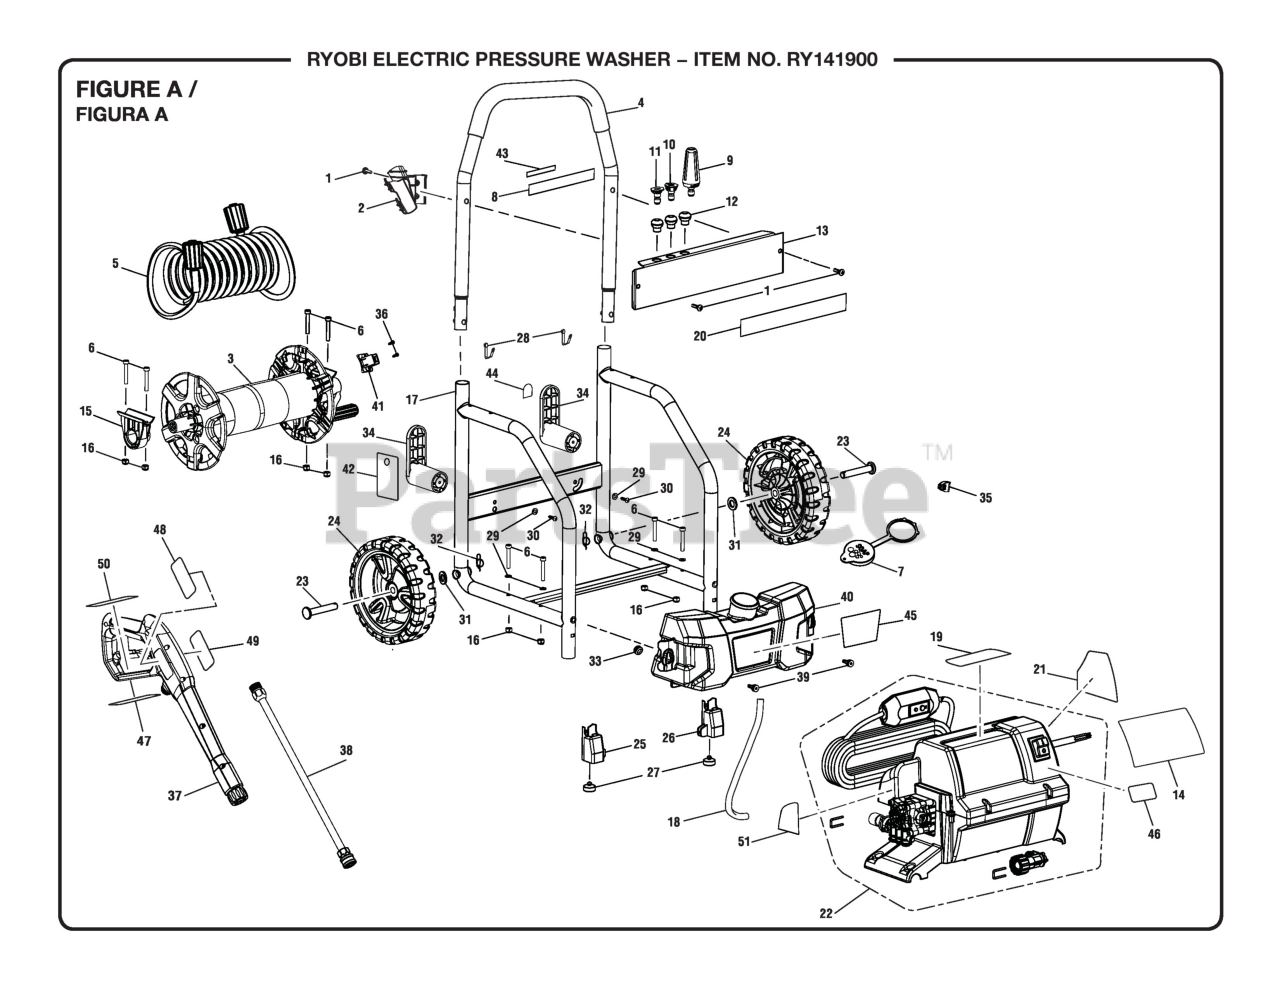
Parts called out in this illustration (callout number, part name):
1	Bolt (M6 x 20 mm, Philips Pan Hd.)
2	Trigger Handle Holder
3	Hose Reel Assembly
4	Handle Assembly
5	Hose (25 ft.) [PS141913]
6	Bolt (M6 x 40 mm, Socket Hex Hd.)
7	Detergent Tank Cap
8	Quick Start Label
9	Turbo Nozzle
10	Soap Nozzle (Blue)
11	Nozzle (15deg)
12	Nozzle Grommet
13	Performance Panel
14	Ryobi Logo Label
15	Bracket (Hose Reel)
16	Lock Nut (M6)
17	Main Frame
18	Injection Hose
19	Nozzle Selection Label
20	Performance Label
21	Danger Label
22	Pump Housing Assembly
23	Wheel Axle
25	Foot (Left)
26	Foot (Right)
28	Nozzle Hangtag (PS141913)
29	Washer (OD12 x ID6.6 x 1.6t)
30	Screw (M4.8 x 19 mm, Phillips Hd. S.T.)
31	Washer (OD24 x ID12.5 x 2.5t)
32	Hitch Pin
33	Soap Tank Grommet
34	Cord Wrap Arm
35	Electric Cord Clip
36	Pump Label
37	Trigger Handle
38	Spray Wand Assembly
39	Shoulder Bolt (M6 x 16 mm)
40	Detergent Tank
41	Hose Clip
42	Warning/Notice Hangtag
43	Inquires Label (Ryobi)
44	Power Cord Unlock Label
45	Detergent Tank Label
46	On/Off Switch Label
47	Trigger Handle Rating Label
48	Trigger Handle Logo Label
49	Trigger Handle Warning Label (English)
50	Trigger Handle Warning Label (French/Spanish)
51	Screw (M4 x 25.4 mm, Flat Hd. S.T.)
